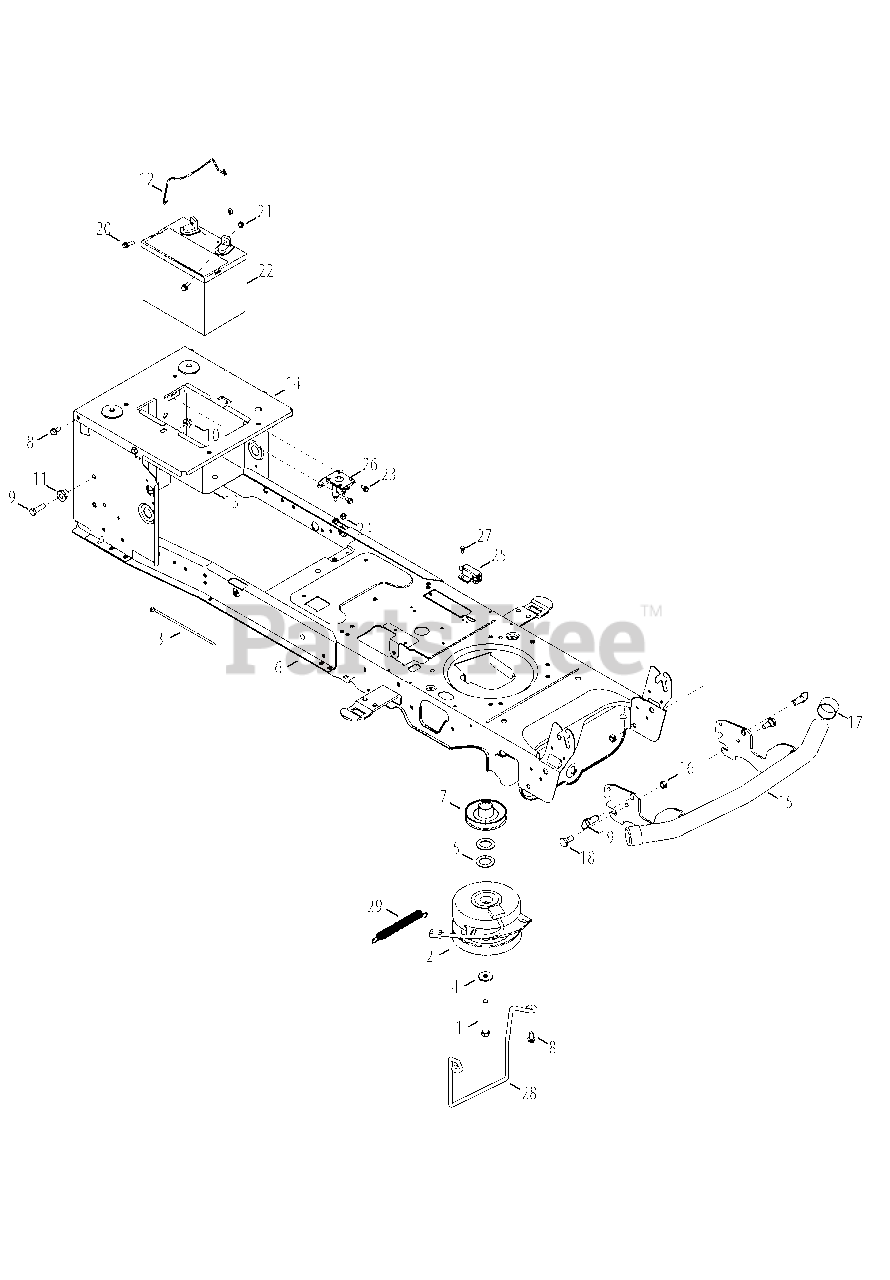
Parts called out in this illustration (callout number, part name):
1	Hex Head Screw, 7/16-20:3.50
2	Electric PTO Clutch
2	Clutch Wire Jumper
3	Cable Tie, 3/16 x .05 x 7.4
4	Washer, Flat, .450 x 1.25 x .164
5	Flat Washer, 1.031 x 1.620 x .095
6	Frame
7	Electric PTO Engine Pulley
8	Taptite Screw, 5/16-18:.750
9	Hex Head Screw, 3/8-16:1.25
10	Flangelock Nut, 3/8-16
11	Shoulder Spacer, .38 x 1.0 x .70
12	Battery Holder Rod
13	Battery Tray
14	Seat Frame Bracket
16	Hex Lock Nut, 3/8-16
17	Bumper Cap
18	Shoulder Bolt, .496 x .336
19	Quick Release Pin
20	Hex Head Flange, 1/4-20:.75
21	Sems Nut, 1/4-20
22	Battery
23	Taptite Screw, 1/4-20:0.375
24	Flangelock Nut, 1/4-20
25	Interlock Switch
26	Solenoid, 12 V
27	Shoulder Screw, #10-32:.500
28	Belt Keeper Rod
29	Spring, Extn, .56 Dia X 5.52
